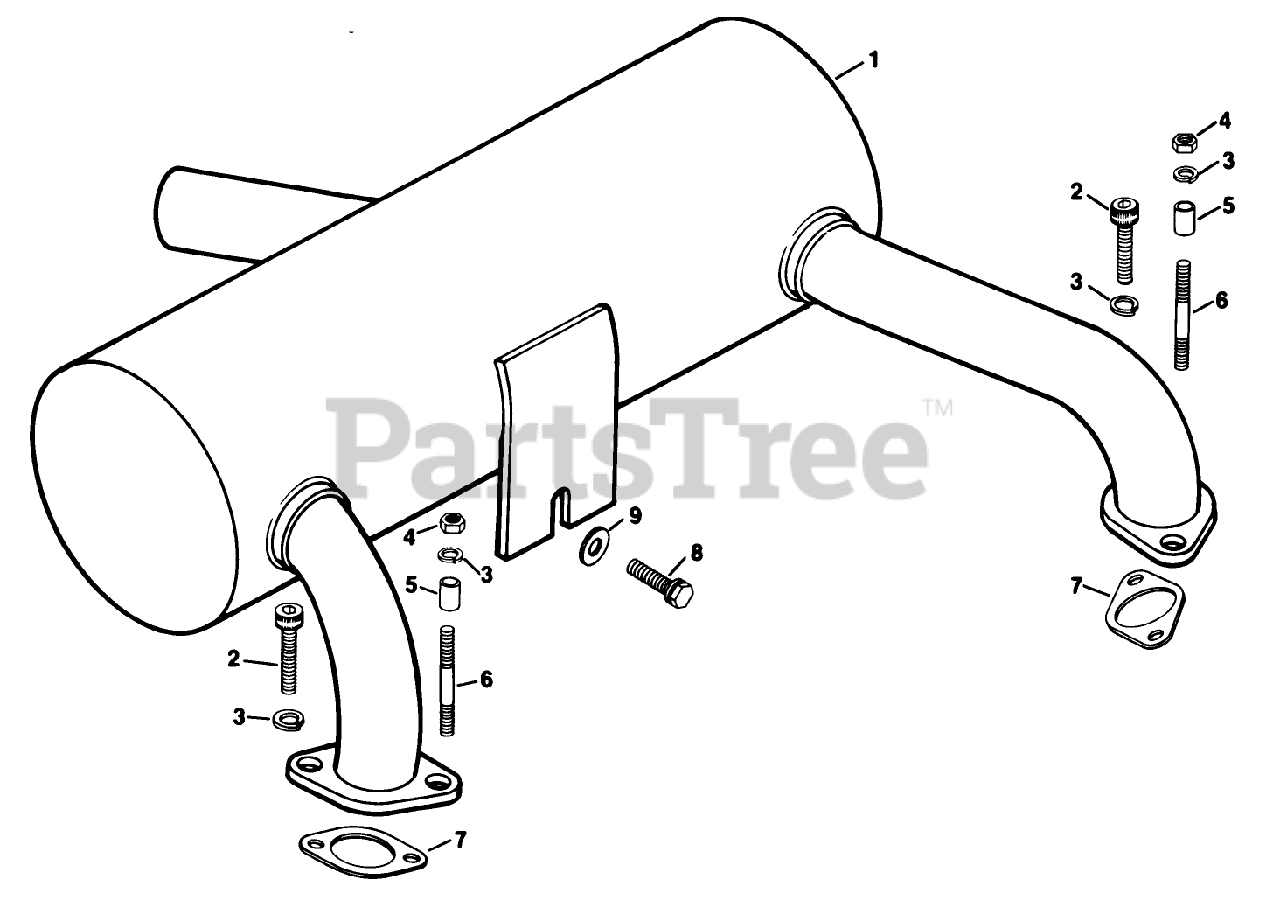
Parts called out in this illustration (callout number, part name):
1	Muffler
2	Screw
3	Washer
4	Nut
7	Gasket Exhaust
8	Screw
9	Washer
